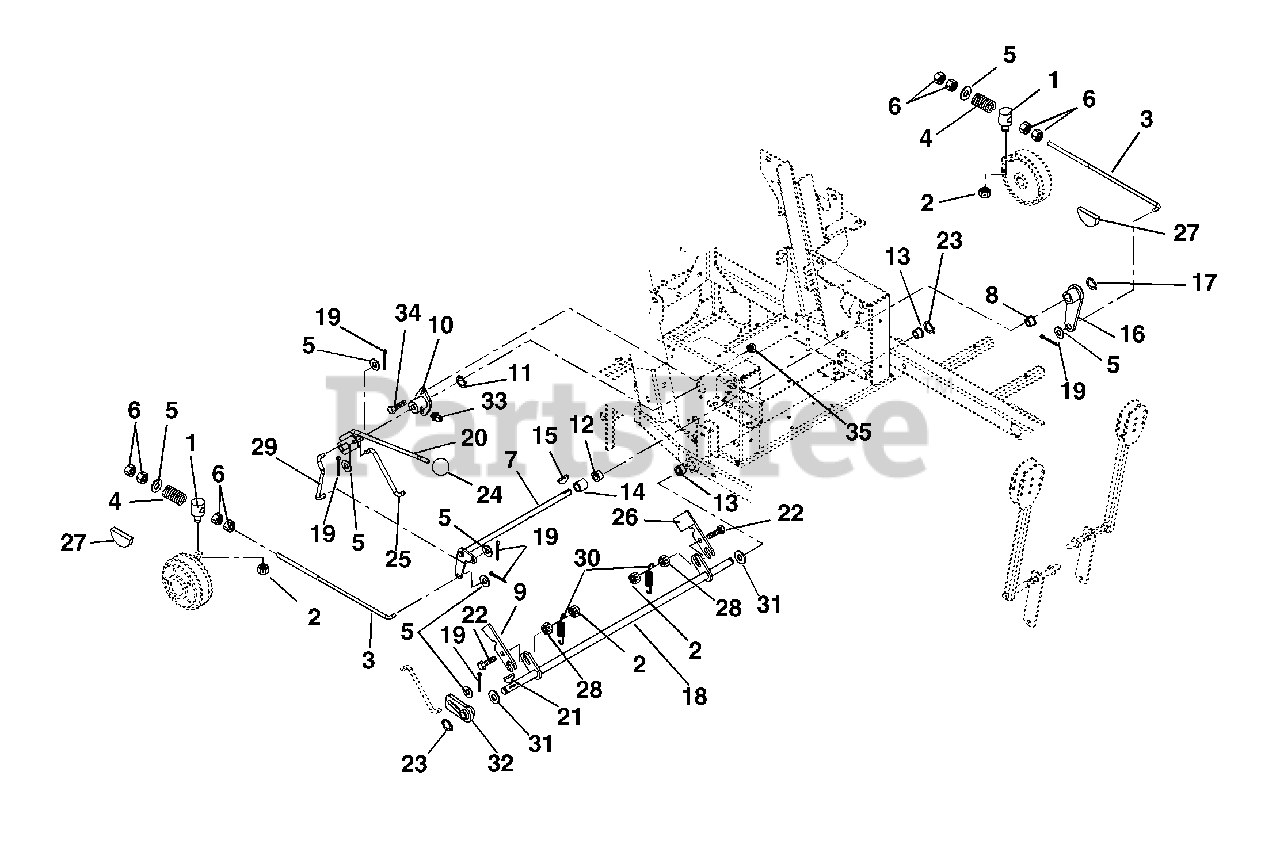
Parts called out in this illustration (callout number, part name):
1	Pivot-Brake Rod
2	Nut-Locking-Center .31-18
3	PTO Link Rod
4	Spring-Compression .143 x .710 x 2.00
5	Washer-Flat-Steel .406 x .812 x .065
6	Nut-Hex .38-16
7	Shaft-Brake Cross
8	Bushing-Flange Nylon .63 x 1.00 x .625
9	Slide, Interlocking Brake
10	Bushing, Flange
11	Ring-Retaining-External .625 x .05
12	Bushing-Flange Nylon .762 x 1.00 x .58 x 1.48
13	Bushing-Flange .50 x .75 x .75 x 1.00
14	Bushing-Sleeve .75 X 1.00 X .75
15	Key-Woodruff .19 x .75 Hard #9
16	Arm-Brake Left-Hand
17	Ring-Retaining-External .625 x .050
18	Weldment, Mechanical Brake
19	Pin-Cotter External .09 x .75
20	Shaft-Brake Actuating
21	Key-Woodruff .13 x .63
22	Bolt-Hex .31-18 x 1.25 Grade 5
23	Ring-Retaining-External .50 x .05
24	Knob, Steering Lock
25	Arm, Brake Lever
26	Interlock, Safety Switch
27	Pad, Disk Brake
28	Nut-Locking-Top-Flange .31-18
29	Linkage, Brake Actuating
30	Spring-Tension .048 x .44 x 1.75
31	Washer-Flat-Steel .505 x 1.00 x .062
32	Weldment, Parking Brake Hub
33	Fitting-Lube .25-28X.256
34	Bolt-Hex .31-18 x .75 Grade 5
35	Nut-Locking-Nylon .312-18
